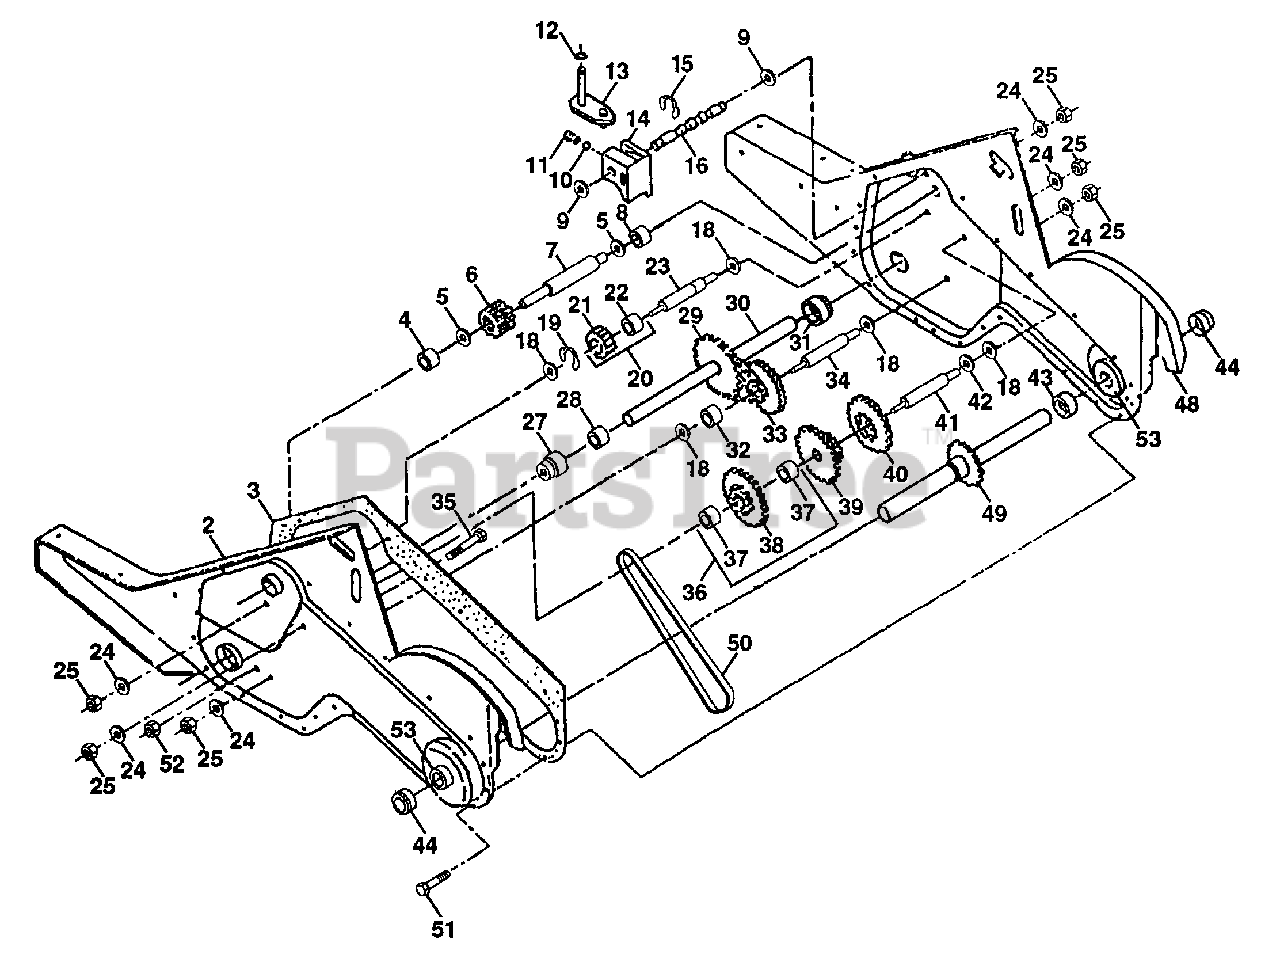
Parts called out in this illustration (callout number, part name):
1	Transmission Assembly
2	Gearcase, L.H. w/Bearing
3	Gasket, Gearcase (AYP part number)
4	Bearing, Needle
5	Washer, Thrust 5/8 x 1.10 x 1/32
6	Pinion, Input
7	Shaft, Input
8	Bearing, Needle (AYP part number)
9	Washer, Seal
10	Ball, Steel (AYP part number)
11	Spring, Shift, Fork (AYP part number)
12	O-Ring (AYP part number)
13	Arm, Shift
14	Fork, Shift
15	Ring, Klip
16	Shaft, Shift
18	Washer
19	Ring, Klip
20	Gear, Assembly, Reverse Idler
21	Gear, Reverse Idler (AYP part number)
22	Bearing, Needle
23	Shaft, Reverse Idler (AYP part number)
24	Washer, Lock 7/16
25	Nut, Hex 7/16-20
27	Bearing, Shaft, Ground Drive L.H.
28	Spacer 0.765 x 1.125 x 1.23 (AYP part number)
29	Chain #35-50 Pitch (AYP part number)
30	Ground Shaft Assembly
31	Bearing, Shaft, Ground Drive R.H.
32	Spacer 0.70 x 1.00 x 1.150 (AYP part number)
33	Sprocket and Gear Assembly (AYP part number)
34	Shaft, Reduction (2nd) (AYP part number)
35	Screw, Whiz, Lock 5/16-18 x 3-1/2 (AYP part number)
36	Sprocket Assembly w/Bearing
37	Bearing, Needle (AYP part number)
38	Sprocket, Tine
39	Gear, Cluster, Red 1st & 2nd (AYP part number)
40	Gear, Reverse (AYP part number)
41	Shaft, Reduction (1st)
42	Washer, Thrust
43	Spacer 1.01 x 1.75 x 0.760
44	Seal Asm. Oil
48	Gearcase, R.H. w/Bearing
49	Shaft, Tine
50	Chain, Roller #50-50 Pitch (AYP part number)
51	Screw 1/4-20 x 1/2
52	Nut, Hex 5/16-18
53	Kit, Bearing (AYP part number)
